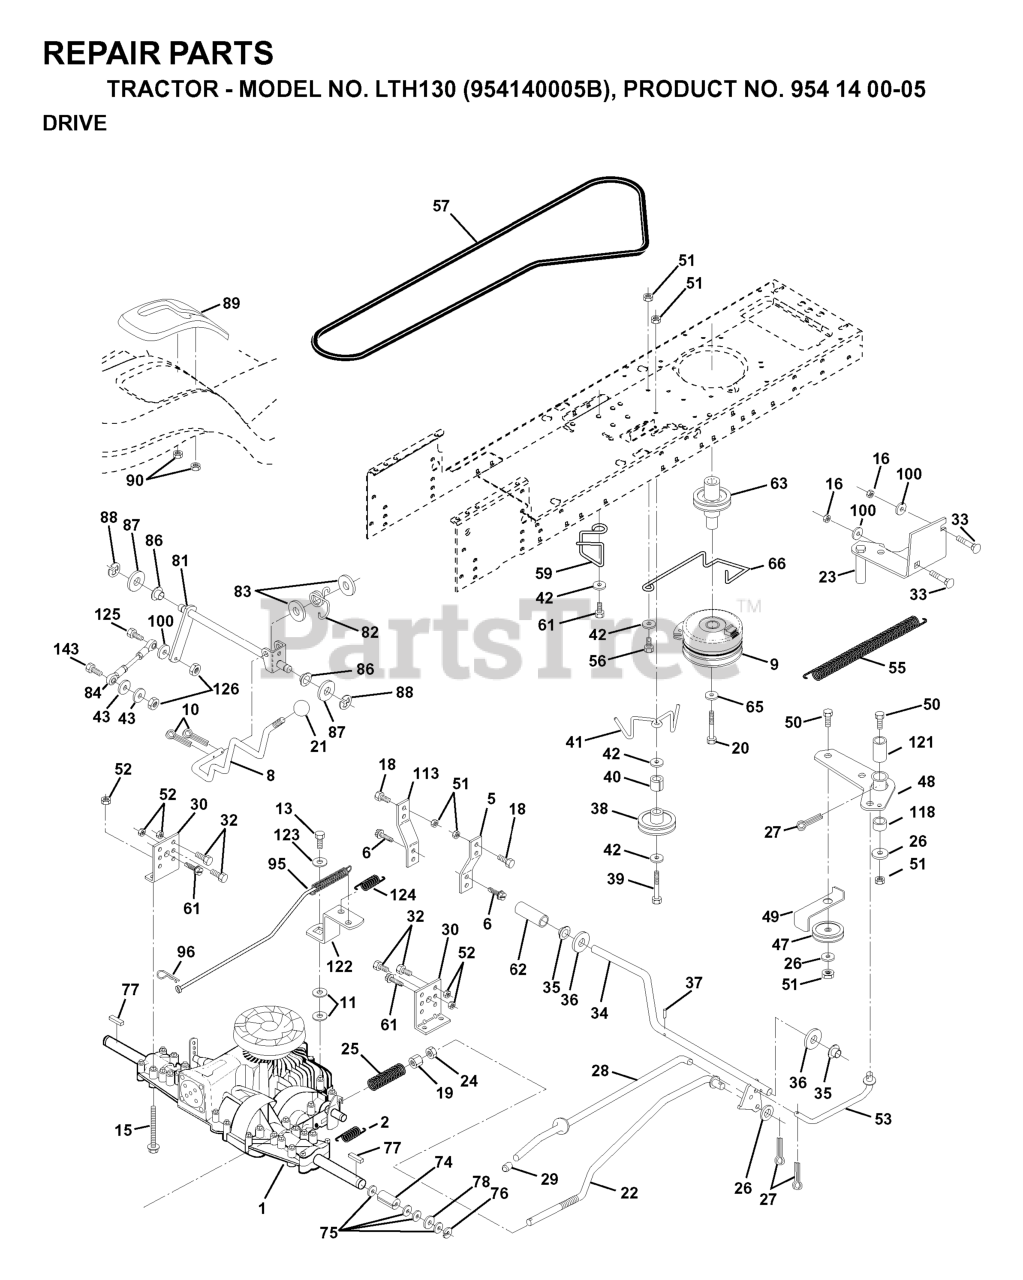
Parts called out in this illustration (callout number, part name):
2	SPRING,BRAKE RETURN
5	STRAP TORQUE
6	SCREW.THDROL.5/16-18X3/4.TTY
8	ROD SHIFT FENDER
9	CLUTCH.ELECT.EVX.
10	PIN COTTER
13	BOLT 1/4-28X3/4
15	BOLT HEX 5/16-18 GR 5
16	NUT.71038.31-18.HEX.NYLOCK
19	NUT
20	BOLT HEX
21	KNOB.DUCKHEAD.1/2
23	BRACKET, ASM CLUTCH MTG
24	NUT
25	SPRING ROD LT
26	WASHER
27	COTTER PIN
28	ROD BRAKE PARK LT
29	PLUNGER CAP
30	BRACKET TRANSAXLE
32	BOLT
33	RP BOLT 5/16-18 X3/4 ZN/YEL GR
34	SHAFT, FOOT PEDAL
35	BEARING.NYLON
37	DRIVE PIN
38	PULLEY.IDLER.FLAT
41	KEEPER, BELT IDLER
42	WASHER
47	IDLER PULLEY
48	BELLCRANK ASSEMBLY
49	RETAIN BELT
50	BOLT
52	LOCKNUT
53	LINK, CLUTCH LT
55	SPRING, RETURN LT
57	RP.V-BELT
59	KEEPER CENTER SPAN
61	SCREW
62	PEDAL COVER T
63	PULLEY, CLUTCH ELECT EVX
65	LOCKWASHER
66	KEEPER BELT ENGINE
77	SQUARE KEY
82	SPRING,TORSION
83	WASHER
86	BUSHING.STEERING.ROD LTB-WSL
89	CONSOLE SHIFT
90	NUT.PUSH.3/16
95	ROD ASM BYPASS PVST
96	RETAINER M
100	WASHER M
113	STRAP TORQUE LH LT
118	SPACER BELLCRANK
121	NYLINER CLUTCHING
122	PLATE BYPASS PVST
124	RETURN SPRING
125	BOLT.FIN.HEX.5/16-18UNC X 1.00
143	BOLT.5/16-18X1-1/4 FULL.THREAD
